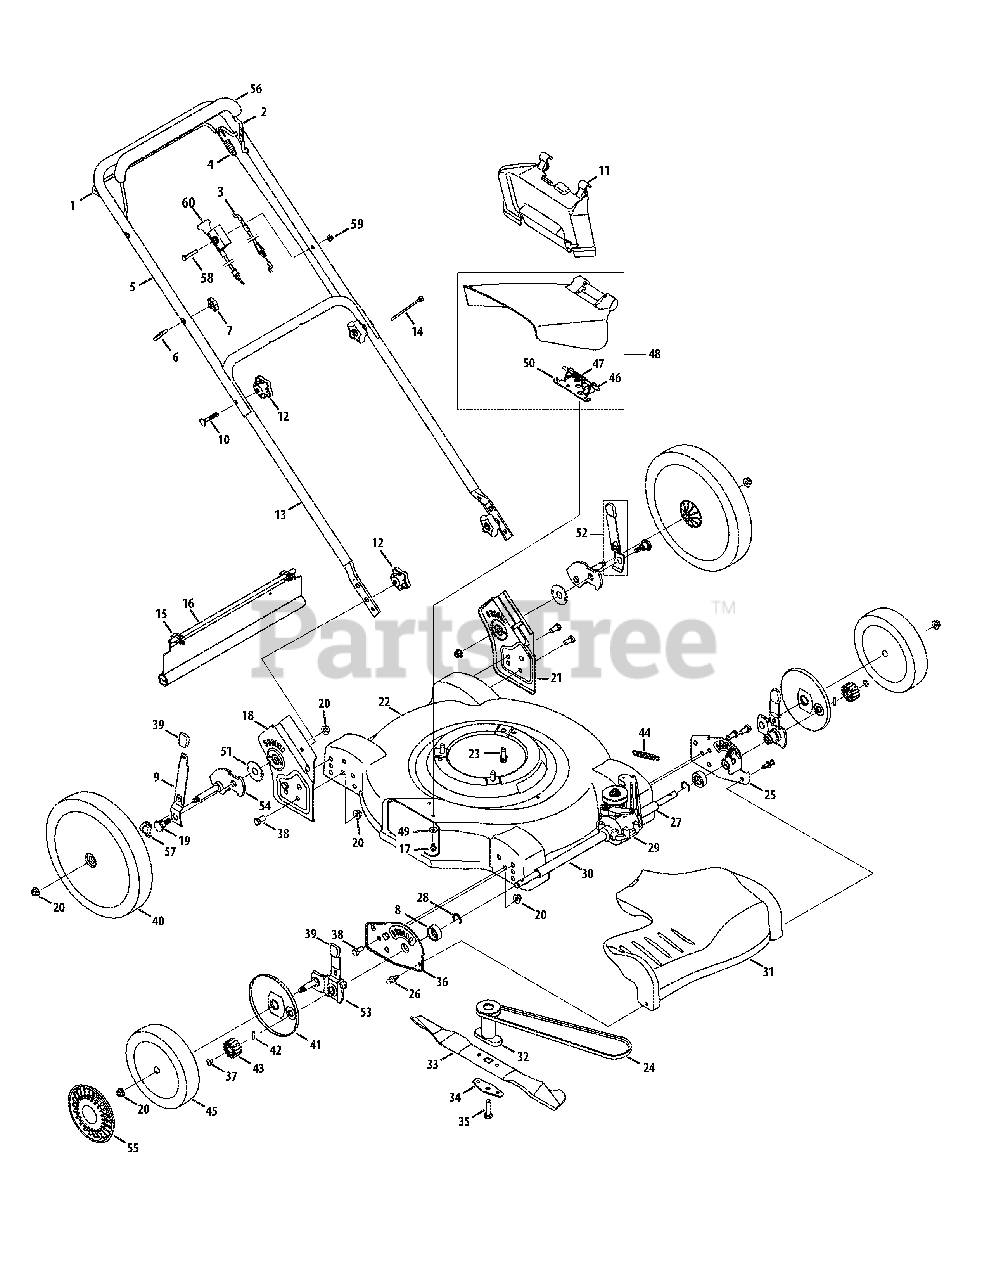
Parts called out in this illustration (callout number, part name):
1	Drive Control
3	Control Cable
4	Drive Control Cable
7	Wing Nut, 1/4-20
8	Bearing Support Spacer
10	Carriage Bolt, 5/16-18 x 2.0
11	Mulching Baffle
12	Star Knob
15	Hinge Clip
16	Trail Shield
17	Hex Screw, 1/4-20 x.500
19	Shoulder Screw, .625 x .412
20	Lock Nut, 3/8-16
23	Hex Washer Scr., 3/8-16 x 1.0
24	V-Belt, 3L x 32.90
27	Sleeve Spacer, .550 ID x 2.22
28	Retainer Ring
29	Transmission Assy. Comp.
30	Sleeve Spacer, .550 ID x 8.51
31	Transmission Cover
32	Blade Adapter
33	22" Mulching Blade
34	Blade Bell Support
35	Hex Cap Screw, 3/8-24 x 1.5
37	Screw, 1/4-20 x .390
38	Hex Cap Screw, 3/8-16 x.75
39	Adjustment Knob
40	Rear Wheel, 12 x 2.125, Zag
41	Wheel Dust Cover
42	Pin
43	Spur Gear 14T - RH
43	Spur Gear 14T - LH
44	Ext. Spring, .47 OD x 2.50
45	Front Wheel, 8 x 2.125, Zag
46	Hinge Pin
47	Torsion Spring
48	Side Discharge Assembly
49	Bell Washer, .265 ID x.75 OD
50	Deflector Chute Adapter
51	Thrust Bearing
52	Rear Hgt. Adj. Lever Assembly
53	Front Lever Assembly -
54	Rear Pivot Arm Assembly - LH
54	Rear Pivot Arm Assembly - RH
55	Hub Cap
56	Deluxe Bail Cover
57	Washer, Spring, .500 x 1.00 x .022
58	Screw, 1/4-20 x 1.50
59	Nut, Flange Lock, 1/4-20
60	Choke Cable
